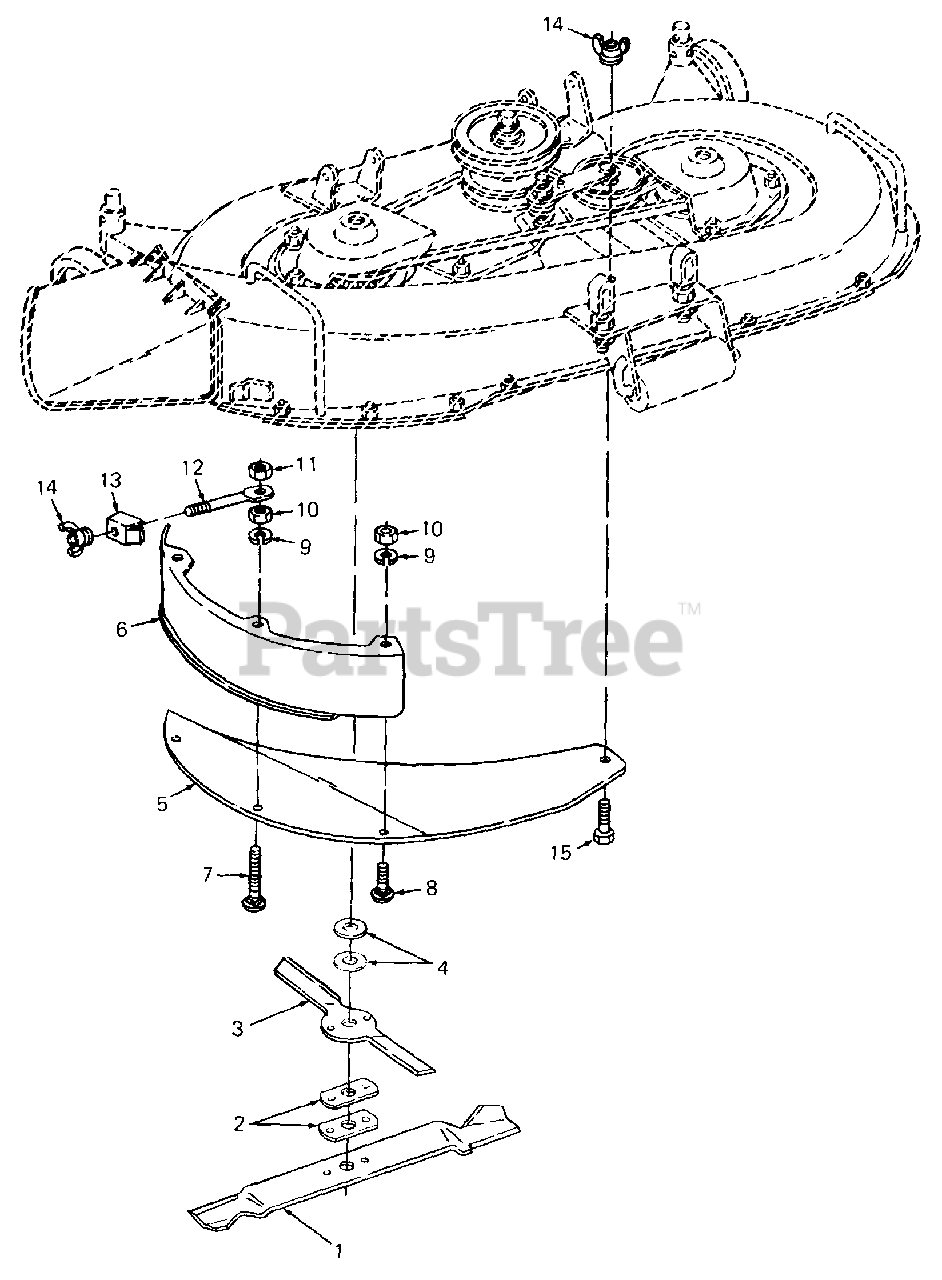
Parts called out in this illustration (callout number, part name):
1	Blade, Low Lift, 21.20 Lg
8	Bolt, Carriage, 1/4-20 X .62 Lg
9	Washer, Lock, 1/4
10	Nut, Hex, 1/4-20 GR5
11	Nut, Hex Center Lock, 1/4-20
12	Bolt, Retaining
14	Nut, Nylon Wing, 1/4-20
15	Screw, Hex Cap, 1/4-20 X .62 Lg
